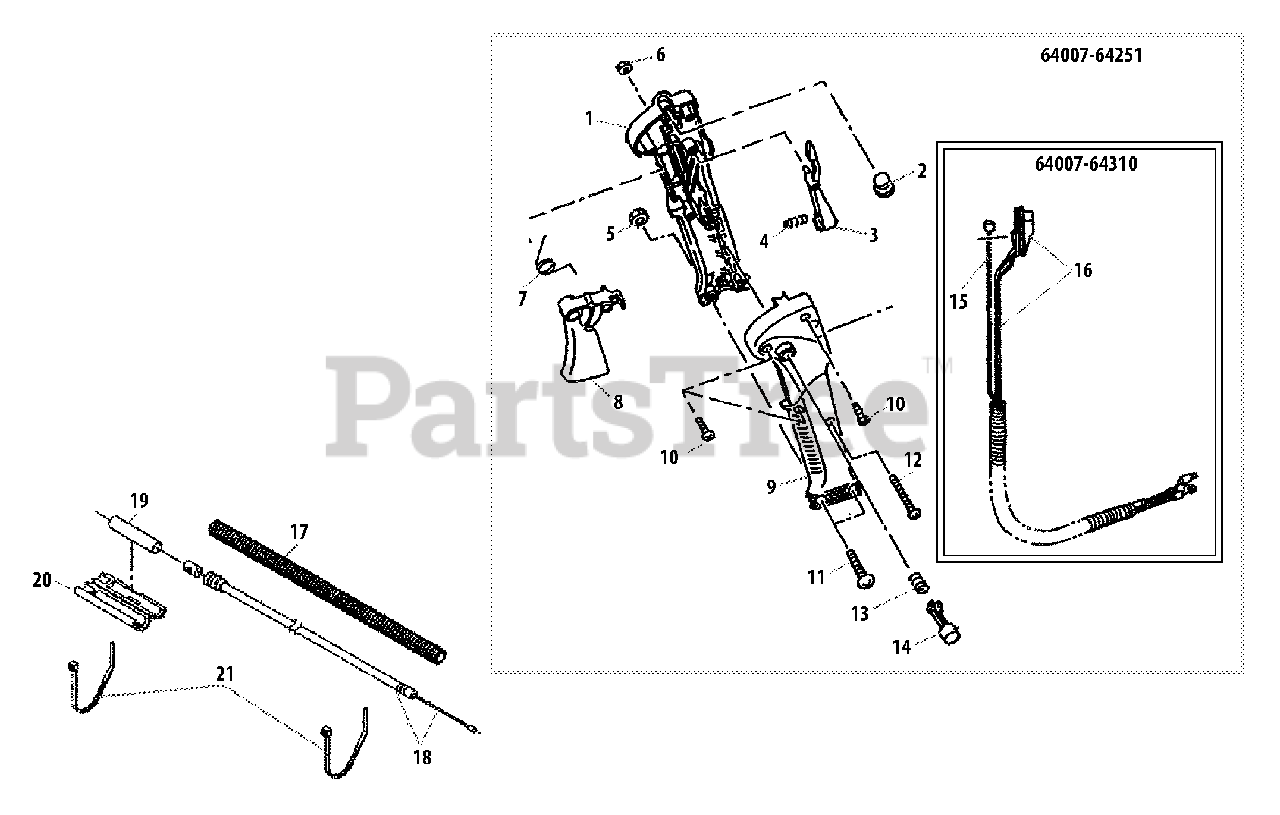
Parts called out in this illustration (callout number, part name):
1	BODY, RIGHT
2	PLUG, RUBBER
3	LOCKOUT, THROTTLE
4	SPRING, COMPRESSION
5	NUT M5
6	NUT M4
7	SPRING, TORSION
8	TRIGGER, THROTTLE
9	BODY, LEFT
10	SCREW - 4×16 -- TAPPING
11	SCREW M5×20
12	SCREW M4×23
13	SPRING, COMPRESSION
14	BUTTON, THROTTLE LOCK
15	CABLE, THROTTLE
16	SWITCH, ON-OFF
17	TUBE, PROTECTIVE - CORRUGATED
18	CABLE, THROTTLE
19	SLEEVE
20	CAP, DUST
21	TIE, CABLE
64007-64251	THROTTLE LEVER ASSY
64007-64310	CABLE ASSY, CONTROL
